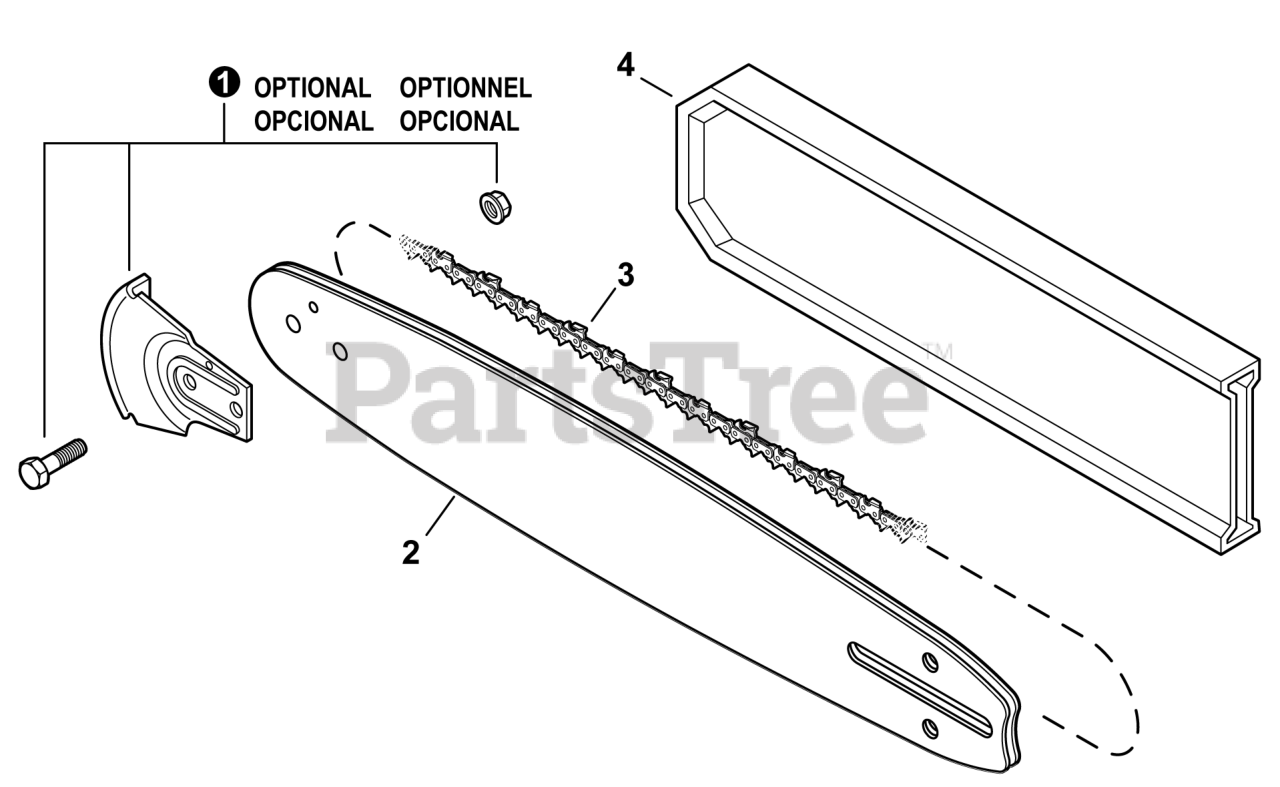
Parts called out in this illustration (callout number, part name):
1	KICK GUARDT KIT
2	GUIDE BAR, 16"
2	GUIDE BAR, 18"
2	GUIDE BAR, 20"
2	GUIDE BAR, 24"
2	GUIDE BAR, 27"
3	SAW CHAIN - 16"
3	SAW CHAIN - 18"
3	SAW CHAIN - 20"
3	SAW CHAIN - 24"
3	SAW CHAIN - 28", 0.050 GAUGE, 3/8" PITCH
4	SCABBARD 16"
4	SCABBARD 18"
4	SCABBARD 20"
4	SCABBARD 24"
